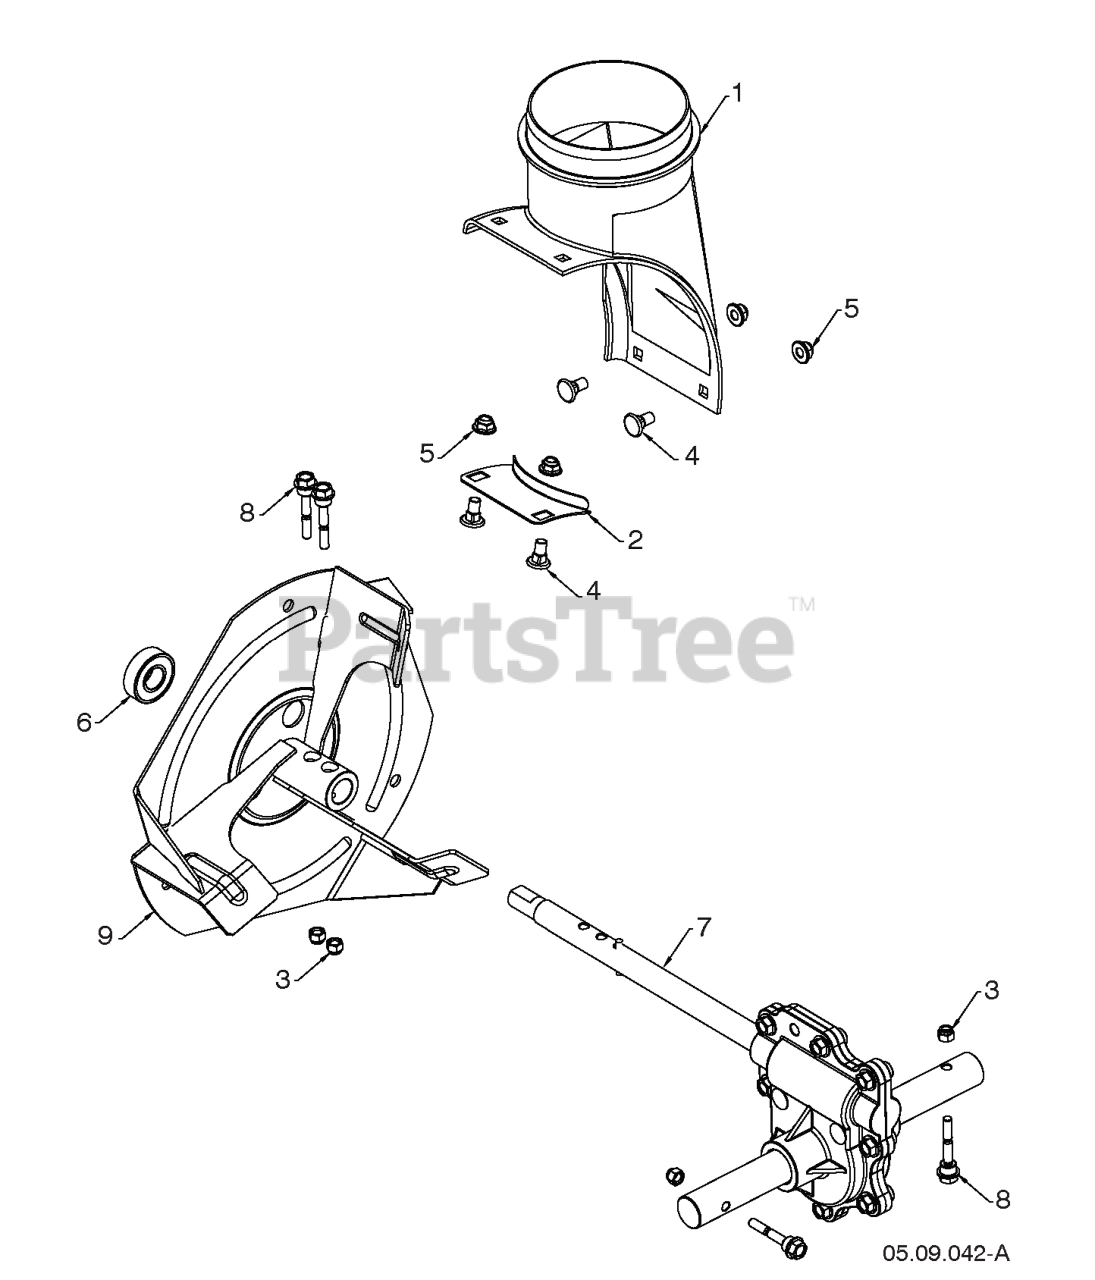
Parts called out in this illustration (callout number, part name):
1	CHUTE.DISCHARGE.BASE
2	BRACKET, CORNER DISCHARGE
3	LOCKNUT.NYLOC.1/4-20
4	BOLT CARR WAFER BLK 5_16-18 X
5	NUT HEX FLG NYLOCK BLK 5_16-1
7	TRANSMISSION.GEARBOX.ALUM.DD
8	BOLT.1/4-20 X 1-13/16 SHEAR
9	IMPELLER.STEEL.SNOW.BLACK
